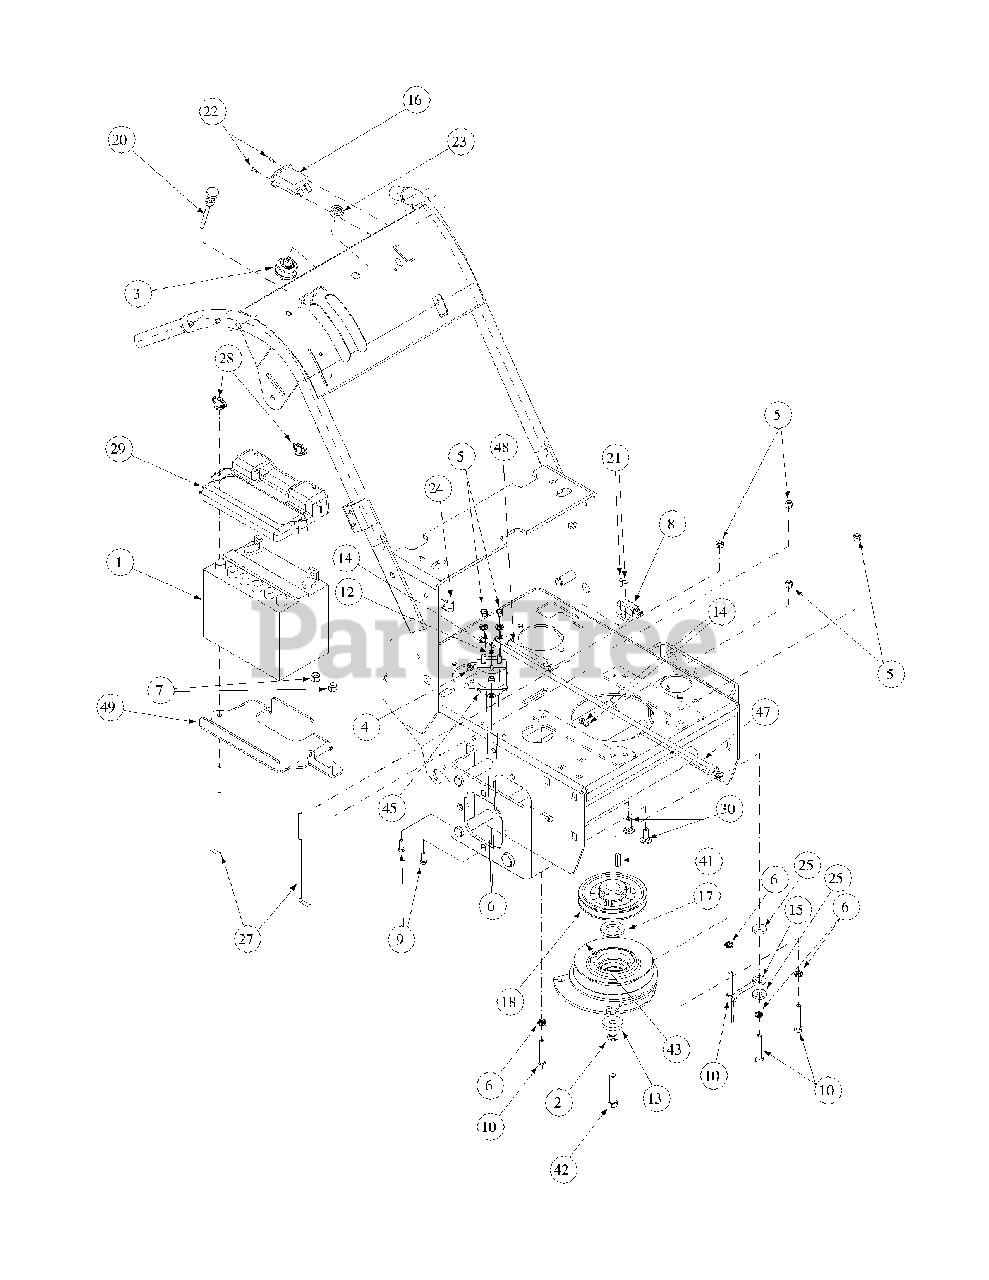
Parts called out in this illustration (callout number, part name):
1	Battery, 12V, 225CCA
2	Lock Washer M10
3	Ignition Switch
4	Lock Nut, Nylon Insert, 1/4-20
5	Nut, 5/16-18, Nylock
6	Lock Washer, 5/16
7	Lock Nut, Nylon Insert, 3/8-16
8	Switch, Delta
9	Cap Screw, 1/4-20 x .75
10	Cap Screw, 5/16-18 x 2
12	Lock Washer, #10
13	Washer Clutch
14	Lock Nut, Nylon Insert, #10-32
15	Guide, Track Drive Belt
16	Hour Meter
17	Washer, Special
18	Sheave 1" Bore w/2 Set Screws
20	Choke Cable
21	Phil. Hd. Mach. Screw, #10-32 x 5/8
22	Rivet
23	Nut, w/Cap, 5/8-32 Ignition
24	Support Clamp 3/8 OD
25	Washer, Idler
27	Hold Down Rod, Battery
28	Wing Nut, 1/4-20 w/Bell Washer
29	Battery Cover, Large
30	Carriage Bolt, 3/8-16 x 2
41	Key, 1/4 x 1/4 x 1
42	Capscrew, M10-1.5 x 60 mm
43	Brake Clutch
45	Solenoid Magnetic Switch
47	Battery Cable, Red 24"
48	Battery Cable, Red 5"
49	Battery Bracket
